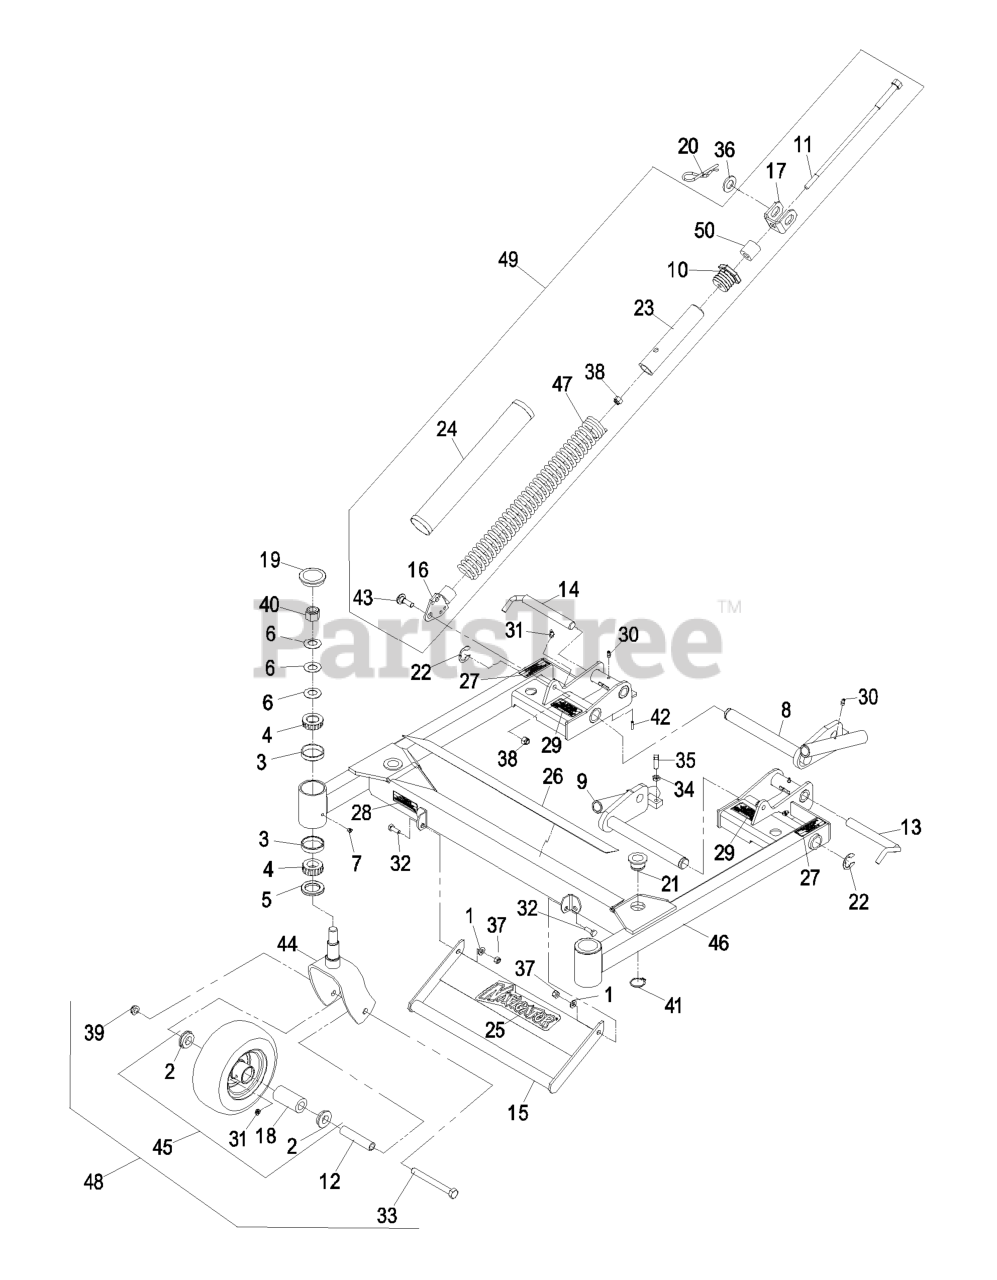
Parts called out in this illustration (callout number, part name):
1	WASHER-SPRING
2	BUSHING
3	CUP-BEARING
4	Cone-Bearing Tapered Roller
5	SEAL-GREASE
6	WASHER-BELLVILLE
8	PIVOT-DECK, RH
9	PIVOT-DECK, LH
10	PLUG-ADJUSTER, SPRING
11	SHAFT-ADJUSTMENT, SPRING
12	SPACER-CASTER, FRONT
13	LOCK-DECK, LH
14	LOCK-DECK, RH
15	ASM,DECK LIFT HANDLE W/DE
16	TENSIONER-SPRING
17	MOUNT-LIFT ASSIST, DECK
18	BEARING-ROLLER, STRAIGHT
19	CAP-GREASE
20	PIN-CUT HEIGHT
21	BUSHING-SUPPORT, DECK
22	RING-SNAP
23	SPRING-TUBE
24	COVER-SPRING, DECK
25	DECAL,NAVIGATOR MODEL
26	PAD-SKID, ANTI
27	DECAL-FOLDING DECK
28	DECAL-DANGER
29	DECAL-SPRING
30	FITTING-GREASE
31	FITTING-GREASE
32	SCREW-HH
33	SCREW-HH
34	NUT-JAM
35	SCREW-SET, SQH
36	WASHER-FLAT
37	NUT-LOCK, NI
38	NUT-LOCK, NI
39	NUT-HEX
40	NUT-LOCK, NI
41	RING-RETAINING
42	PIN-SPRING
43	SCREW-SHOULDER, HWH
44	FORK-CASTER
45	ASM,WHEEL,TIRE & BRGS 8X3
46	DECK SUPPORT ASM
47	SPRING-EXTENSION
48	ASM,FF CASTER WHEEL W/AXL
49	ASM,LIFT AST SPRING
50	SPACER (PLATED)
